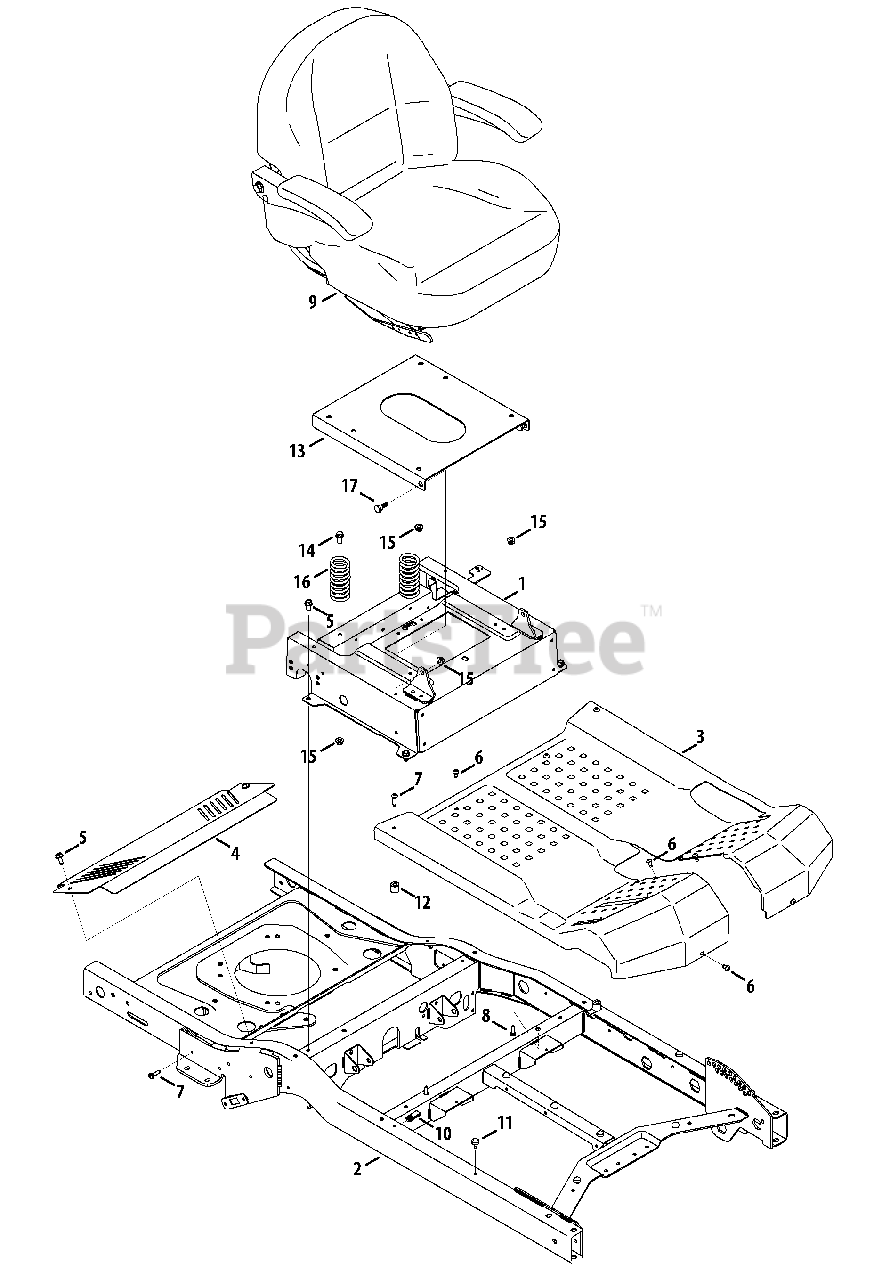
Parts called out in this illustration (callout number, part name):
1	Seat Mount Frame
2	Frame Assembly
4	Transmission Cover
5	Hex Washer Screw, 5/16-18 x .750
6	Screw, 1/4-20 x .5
7	Screw, 1/4-20 x 1.0
8	Screw, 1/4-20 x .625
9	Seat w/ Arms
10	Speed Nut, 1/4-20, U-Type
11	Bumper, .62 x .22
12	Spacer, .281 x .750 x .680
14	Hex Washer Screw, 5/16-18
15	Flange Lock Nut, 5/16-18
16	Comp. Spring, 1.71 x 3.735 x .238
17	Shoulder Screw, 5/16-18 x .437 x .268
